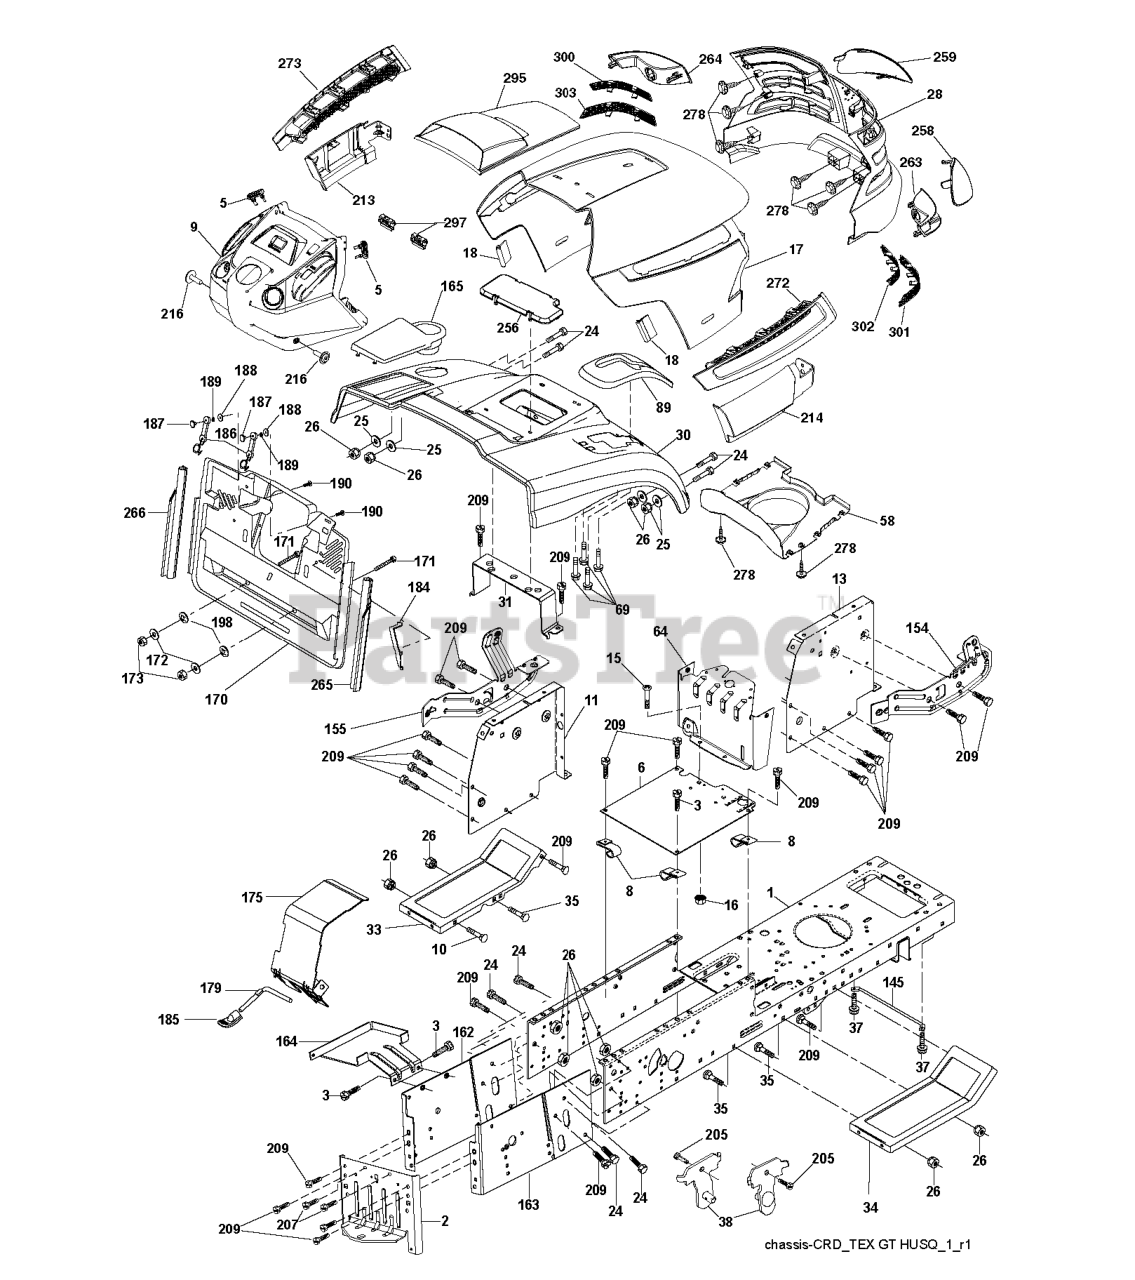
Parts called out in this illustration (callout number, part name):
2	DRAWBAR
3	SCREW 3/8-16X3/4
5	BUMPER DASH
6	PLATE
8	CLIP,INSULATOR
10	BOLT D
11	PANEL DASH LH
13	PANEL DASH RH
15	Screw, Machine, Truss Head 5/16-18 UNC x 3/4
16	NUT
17	HOOD
18	BUMPER.HOOD.TEX.HUSQVARNA
25	WASHER
26	NUT
28	GRILL.ASM.HUSQ.TG/CRD.W/TRIM
30	CONSOLE.CRD.AUTO.GRY
31	BRACKET SUPPORT FENDER
33	FOOTREST PNT LH
34	FOOTREST PNT RH
37	Screw 5/16-18 x 1/2 Hex, Self Tapping 5/16-18 x 1/2
38	BRACKET ASM PIVOT MOWER REAR
58	AIR.DUCT.HOOD.TEX.GT.HUSQ
69	SCREW.HI-LO.CONSOLE
89	CONSOLE.CRD.AUTO.GREY.2005
145	ROD.PIVOT.HOOD
162	BRACKET
163	BRACKET EXTEN CHASSIS RH CRD
165	COVER.BATTERY.BGGR.ELE
172	WASHER
175	DOOR TRAP
179	ROD PIVOT FBI
184	BRACKET.ACTUATOR.BAGGER.SRD
186	LATCH ASSY
187	WELDNUT
189	LOCKWASHER #10
190	SCREW
207	SCREW, 5/16-18 X 1/2
209	SCREW, 3/8-16X3/4
213	SKIRT.HOOD.SIDE.HUSQ.LH.GREY
214	SKIRT.HOOD.SIDE.HUSQ.RH.GREY
216	SCREW 14-20 X 5/8
256	COVER FENDER CRD
258	LENS.RH.TEX.GT.HUSQ.CL
259	LENS.LH.TEX.GT.HUSQ.CL
263	BEZEL.RH.TEX.GT.HUSQ
264	BEZEL.LH.TEX.GT.HUSQ
265	SEALING
266	SEALING
272	VENT.SIDE.HOOD.HUSQ.RH.GREY
273	VENT.SIDE.HOOD.HUSQ.LH.GRAY
278	SCREW.#10 X 0.750.BOS
295	HOOD VENT
297	CLIP.RETAINER.TINNER.
300	INSERT.HEX.GRILL.HUSQ.
301	INSERT.HEX.GRILL.HUSQ.GREY
302	INSERT.HEX.GRILL.HUSQ.
303	INSERT.HEX.GRILL.HUSQ.
